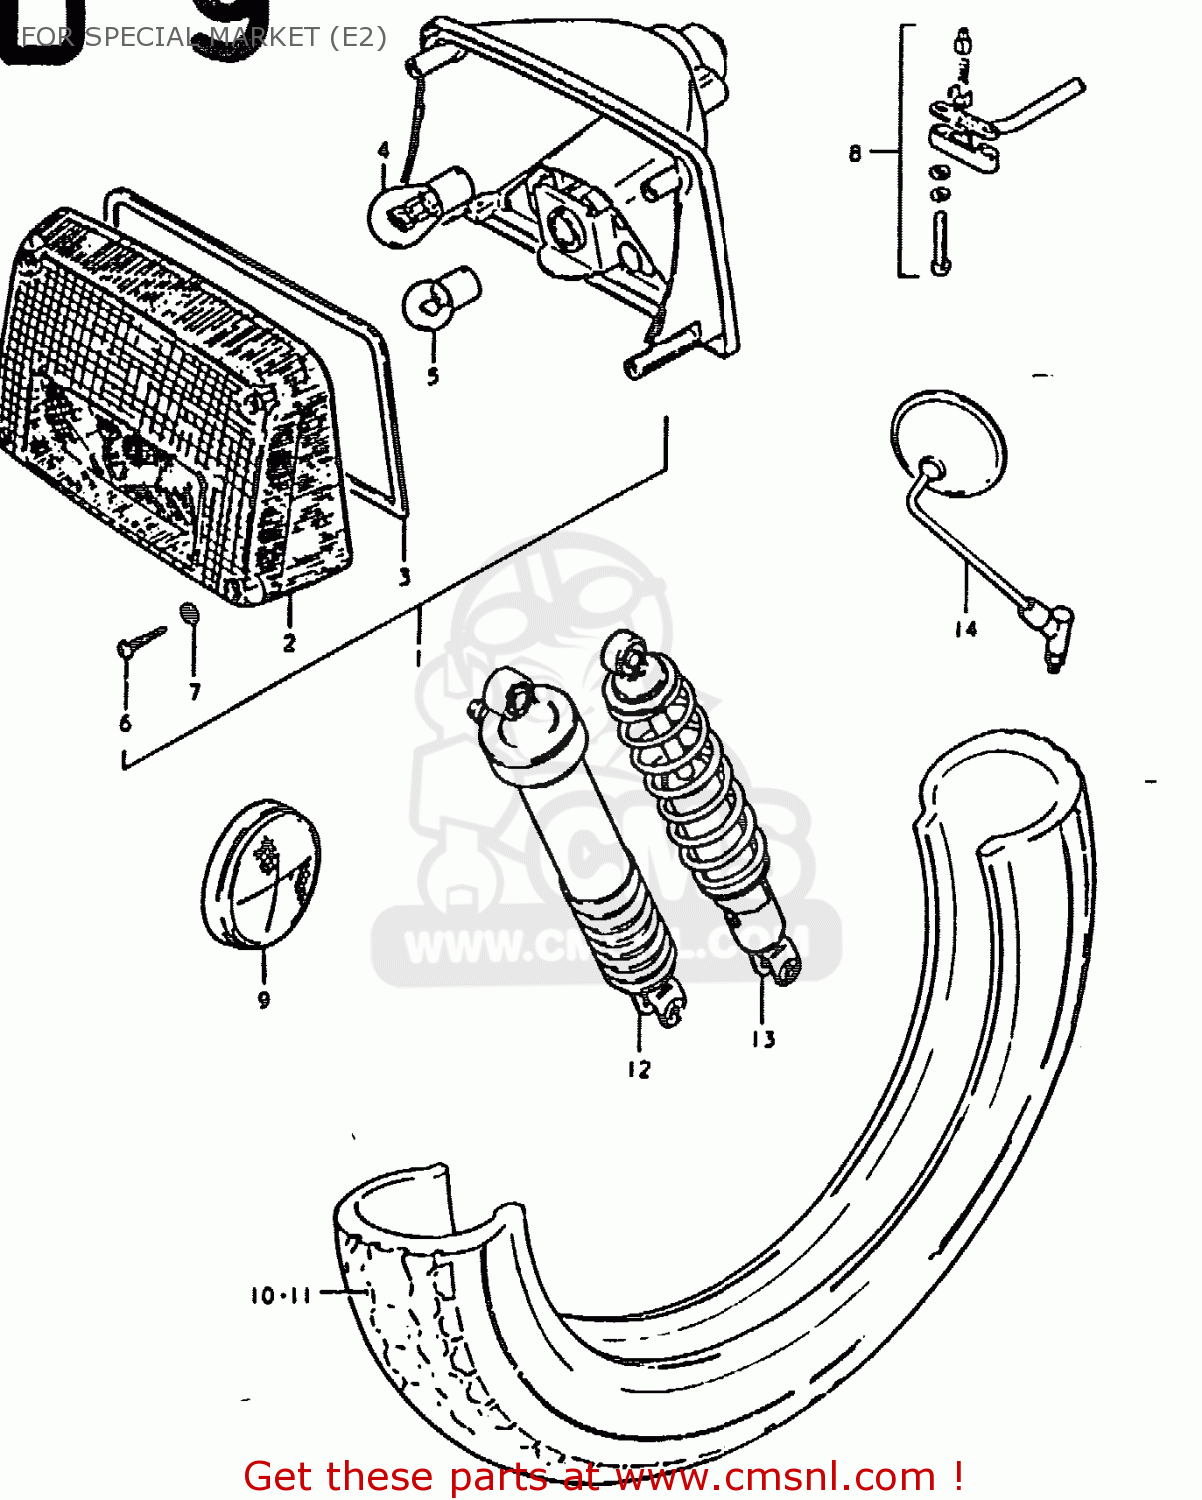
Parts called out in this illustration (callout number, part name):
1	LAMP ASSY, REAR COMBINATION
2	LENS
3	GASKET (NAS)
4	BULB 12V21/5W
5	BULB
6	SCREW
7	GASKET (NAS)
8	SWITCH ASSY,STOP
9	REFLEX REFLECTOR,RR
10	TIRE,FRONT
11	TIRE, REAR
13	SHOCK ABSORBER, REAR
14	MIRROR ASSY,RH
